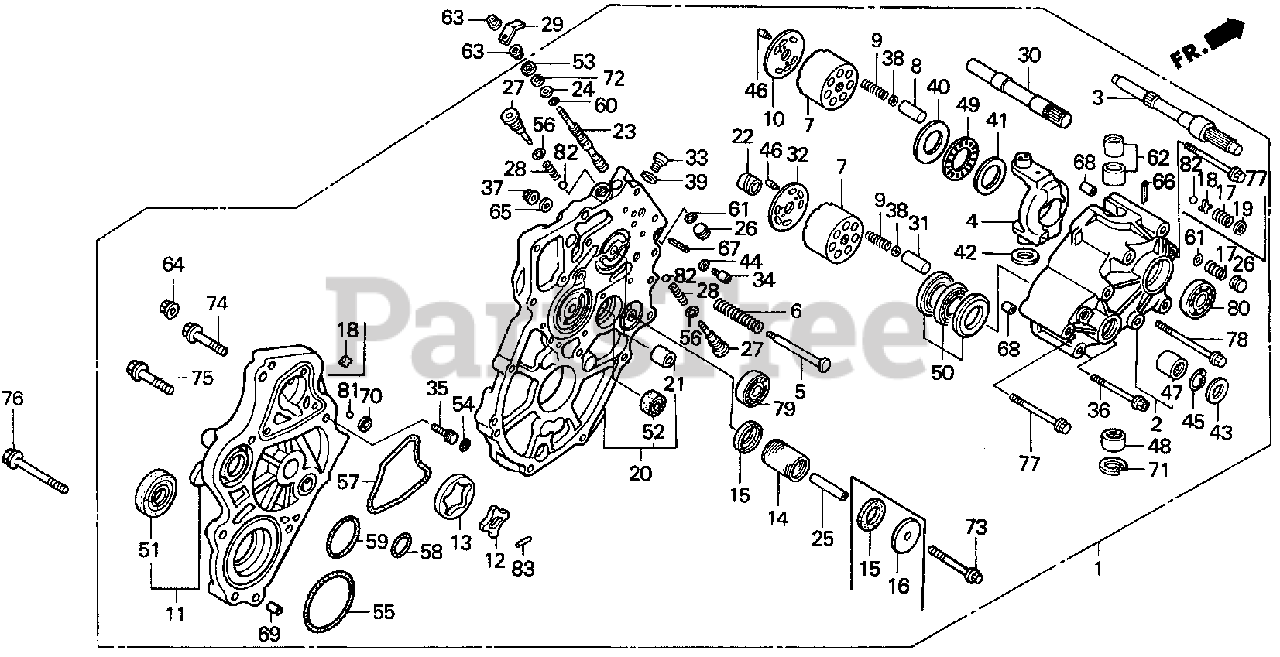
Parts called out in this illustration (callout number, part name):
1	TRANSMISSION SUB-ASSY. (H.S.T.)
2	CASE, PUMP
3	SHAFT, PUMP
4	BOWL, PUMP CONTROL
5	SHAFT, RETURN
6	SPRING, RETURN
7	CYLINDER, PUMP
8	PISTON, PUMP
9	SPRING, PISTON
10	PLATE, PUMP CYLINDER
11	CASE SET, CHARGE
11	CASE, CHARGE PUMP
12	ROTOR, TROCHOID
13	VANE, TROCHOID
14	FILTER, SUCTION (NOT AVAILABLE)
14	FILTER, SUCTION
15	CAP, FILTER GUIDE
16	WASHER, FILTER GUIDE
17	SPRING, RELIEF VALVE (NOT AVAILABLE)
17	SPRING, RELIEF VALVE
18	GUIDE, RELIEF VALVE SPRING (NOT AVAILABLE)
19	WASHER, RELIEF VALVE
20	PLATE, DISTRIBUTOR
21	BUSH, PUMP SHAFT
22	BUSH, MOTOR SHAFT
23	SPOOL, NEUTRAL VALVE
24	COLLAR, NEUTRAL VALVE
25	COLLAR, FILTER SETTING
26	CAP, NEUTRAL VALVE
27	BOLT, CHECK VALVE
28	SPRING, CHECK VALVE
29	LEVER, SPOOL SHIFT
30	SHAFT, MOTOR
31	PISTON, MOTOR
32	PLATE, MOTOR CYLINDER
33	BOLT, SPECIAL (10X13)
34	BOLT, SPECIAL (8X9)
35	BOLT, ADJUSTING (8MM)
35	BOLT, ADJUSTING (6X33)
36	BOLT, FLANGE (8X73)
37	NUT, U (6MM) (FUSE RASHI)
38	WASHER, PISTON (5MM)
39	WASHER, SEALING (10MM)
40	BEARING, PLATE
41	PLATE, NEEDLE BEARING
42	WASHER (20.5X32X3)
43	WASHER, THRUST (17.5MM) (NOT AVAILABLE)
44	WASHER, SEALING (8MM)
45	CLIP, BEARING
46	PIN, DOWEL (4X3)
47	BEARING, NEEDLE (17X24X15) (SOURCE: VINTAGE PARTS INC.)
48	BEARING, NEEDLE (20MM) (NOT AVAILABLE)
49	BEARING, THRUST ROLLER
50	BEARING, THRUST BALL
51	OIL SEAL (20X38X10)
52	OIL SEAL (20X31X7)
53	DUST SEAL (5X14X3)
54	O-RING (4.8X1.9)
54	O-RING (6.8X1.9)
55	O-RING (69.5X3) (ARAI)
55	O-RING (3X70)
56	O-RING (11.8X2.4)
57	O-RING (2.4)
58	O-RING (22.5X2.4)
59	O-RING (34X2.4)
60	O-RING (P7)
61	O-RING (8.8X1.9)
61	O-RING (P9)
62	COLLAR, CONTROL BOWL
63	NUT, FLANGE (5MM)
64	NUT, FLANGE (6MM)
64	NUT, FLANGE (8MM)
65	WASHER, PLAIN (6MM)
66	PIN, SPLIT (3.0X25)
66	PIN, SPLIT (3.0X45)
67	PIN, SPLIT (4.0X28)
67	PIN, SPLIT (4.0X30)
68	PIN, DOWEL (6X10)
69	PIN, DOWEL (8X14)
70	CIRCLIP (INNER) (12MM)
71	CIRCLIP (INNER) (28MM)
72	CIRCLIP (INNER) (14MM)
73	BOLT, FLANGE (6X75)
74	BOLT, FLANGE (8X30)
75	BOLT, FLANGE (8X40)
76	BOLT, FLANGE (8X50)
77	BOLT, FLANGE (8X80)
78	BOLT, FLANGE (8X95) (SOURCE: VINTAGE PARTS INC.)
79	BEARING, RADIAL BALL (6004)
80	BEARING, RADIAL BALL (6203)
81	BALL, STEEL (#10) (5/16)
82	BALL, STEEL (#13) (13/32)
83	ROLLER (3X15.8)
83	ROLLER (3X16.8)
